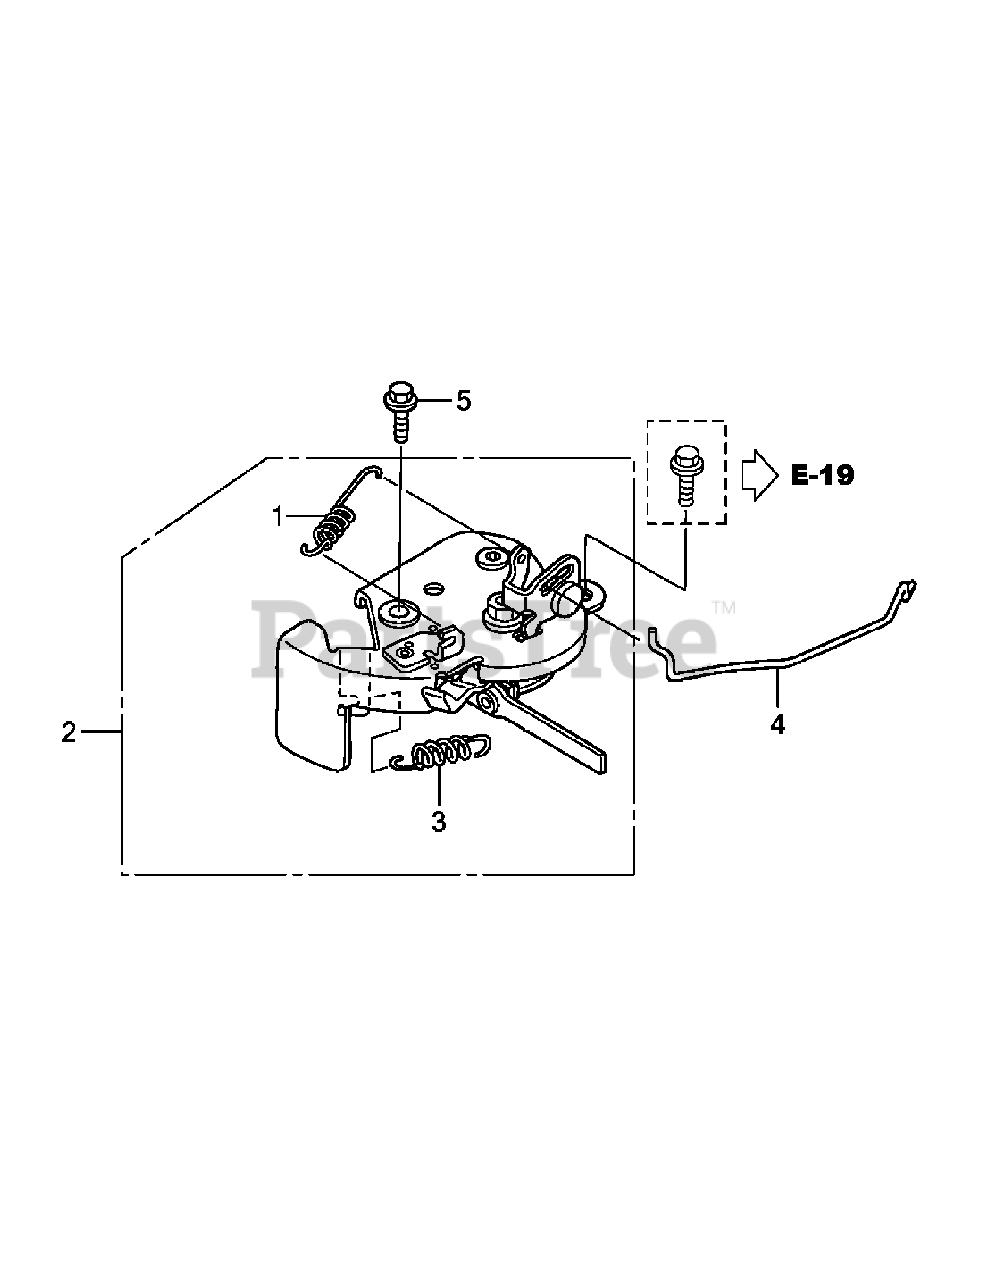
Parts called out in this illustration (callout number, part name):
1	Return Spring
2	Choke Lever Assembly
3	Choke Lever Spring
4	Stop Rod
5	Flange Bolt, 6 x 20 (CT200)
